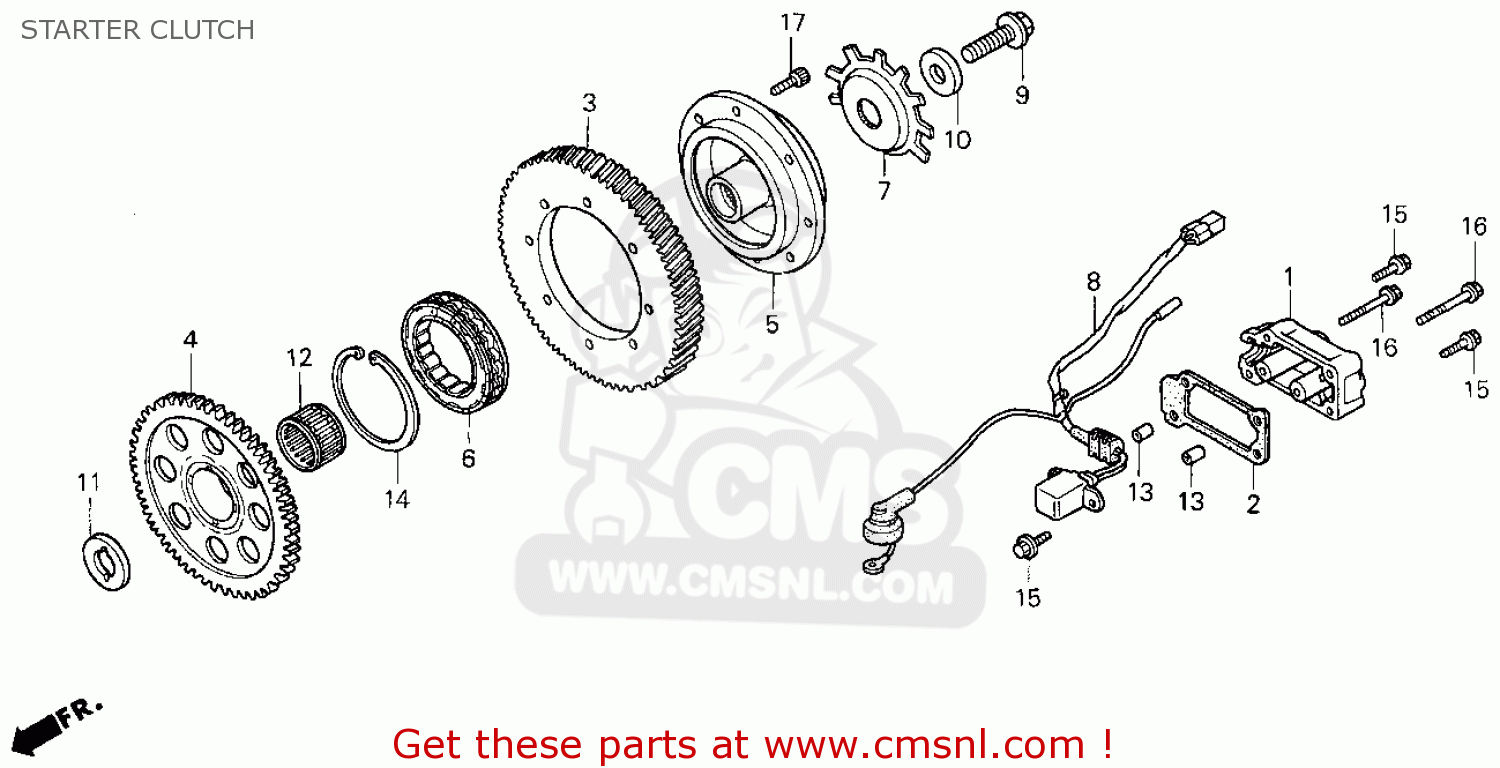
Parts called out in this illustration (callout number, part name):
1	COVER,PULSE
2	GASKET,PULSE COVE (NAS)
3	GEAR,GENERATOR DR
4	GEAR COMP.,STARTE
5	OUTER,STARTING CL
6	CLUTCH,ONEWAY
7	ROTOR,PULSE
8	PULSE GEN ASSY
9	BOLT FLANGE,UBS 1
10	WASHER,12.5X35X5
11	WASHER,THRUST 30X
12	BRG,NDL.40X45X26.
14	CIRCLIP,IN,75
15	BOLT,FLANGE,6X28
16	BOLT,FLNAGE,6X35
17	BOLT,SOCKET 6X14
